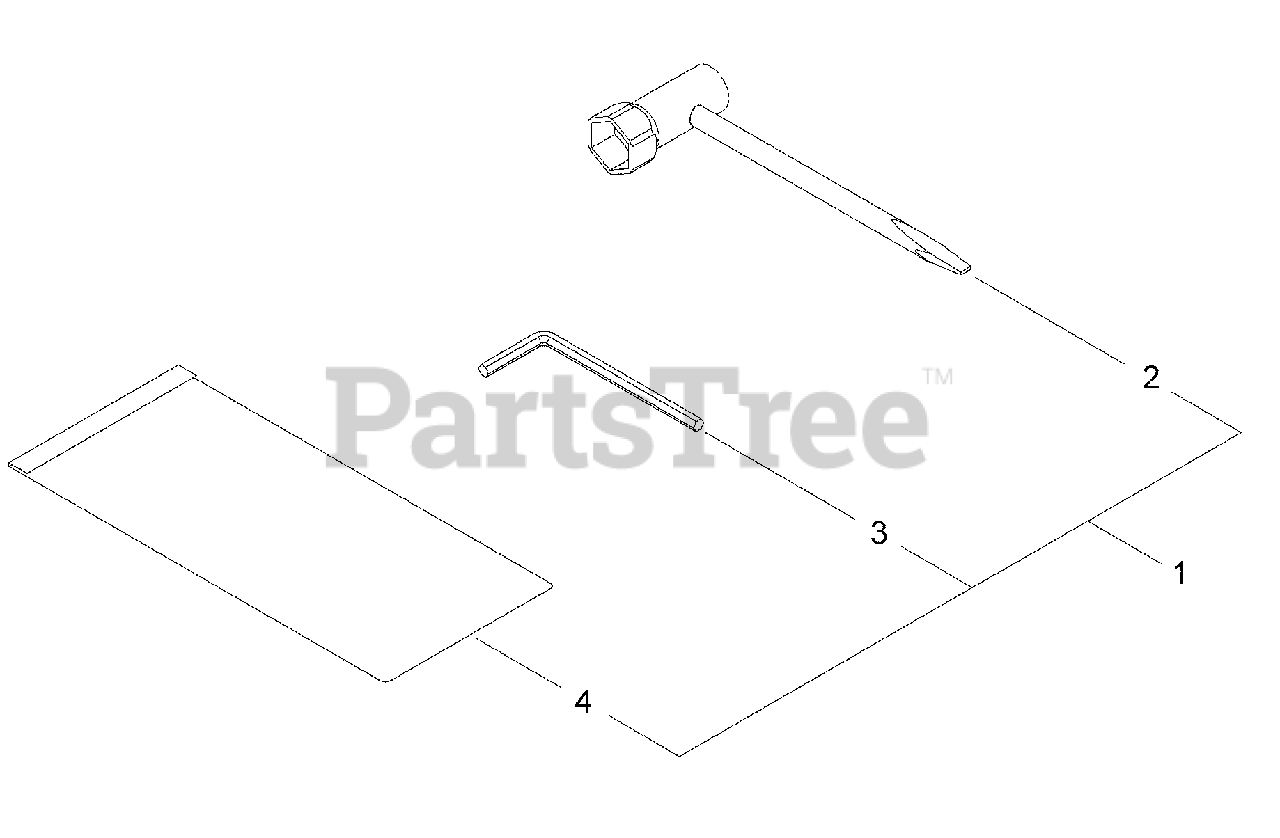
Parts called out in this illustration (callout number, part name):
1	TOOL KIT, SERVICE
2	T-WRENCH 16×13
3	WRENCH, ALLEN 4 MM
4	BAG, TOOL
